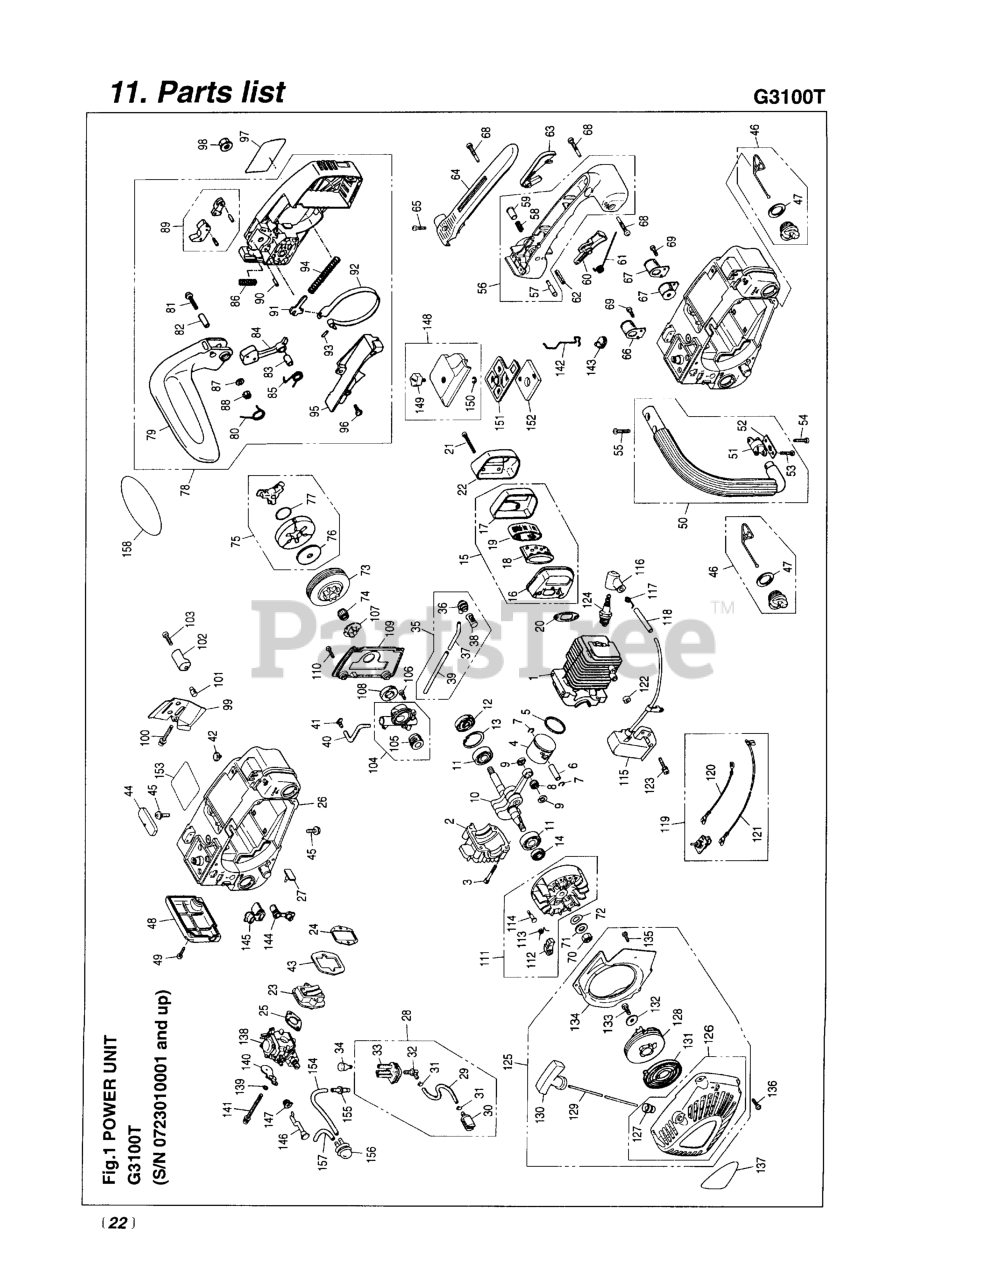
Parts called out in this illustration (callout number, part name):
1	CYLINDER
2	CRANKCASE
3	BOLT, M5 X 30
4	PISTON
5	RING
6	PIN, PISTON
7	RING, SNAP
8	BEARING
9	WASHER (RPLS 3310-41341)
10	CRANKSHAFT
12	SEAL, OIL
13	RING, SNAP, M32 x 1.2
14	SEAL, OIL (RPLS 1100-21210)
15	MUFFLER ASS
17	COVER
18	BAFFLE
19	ARRESTER
23	VALVE ASSEMBLY
25	GASKET
28	FUEL PIPE ASSY
29	PIPE (USE -85411)
30	5500-85400 (RRLS. 1750-85300)
31	CLIP (REPLACES 2841-31280)
34	BREATHER ASSY (RPLS 2630-31270
36	GROMMET (RPLS -31320)
37	JOINT
39	PIPE (USE -85411)
40	PIPE (USE -85411)
41	PIN
42	VALVE A
43	SEAL
45	SCREW
47	GASKET
48	COVER (RPLS -31912)
49	SCREW
50	FRONT HANDLE ASSY (50040056)
51	JOINT (RPLS -32120)
52	STOPPER (RPLS -32150)
57	STOPPER
59	KNOB
61	SPRING
65	SCREW
66	JOINT (RPLS -33510)
67	JOINT(C)(SOFT)
69	SCREW (REPLACES 50030272)
73	DRUM (RPLS 2631-51111)
77	SPRING
81	SCREW
83	SPACER (RPLS -54210)
88	NUT (B)
89	LEVER, BRAKE COMPLETE
91	ARM, SLIDE(RPLS 2670-54410)
92	BAND
93	PIN
94	SPRING, BRAKE (RPLS. 50030121)
95	COVER SPRING
96	SCREW (REPLACES 50030272)
98	NUT
102	CATCHER, CHAIN (RPLS. -53411)
105	GEAR
107	PLATE
108	SEAL
109	COVER, PUMP (RPLS -55311)
110	SCREW
115	MODULE (RPLS 2631-71111)
116	CAP
117	SPRING
118	TUBE
119	SWITCH SET
120	WIRE, LEAD
123	BOLT
127	GUIDE (RPLS -75120)
135	SCREW (REPLACES 50030272)
136	SCREW
138	CARBURETOR ASSY
140	PLATE, CHOKE
142	ROD, THROTTLE (RPLS 2630-)
143	GROMMET
144	GROMMET A
145	GROMMET(B)
146	ROD (RPLS -82310)
147	GROMMET
150	RING, SNAP, M4
154	PIPE
155	JOINT (USE 3350-34320)
156	PUMP ASSEMBLY
